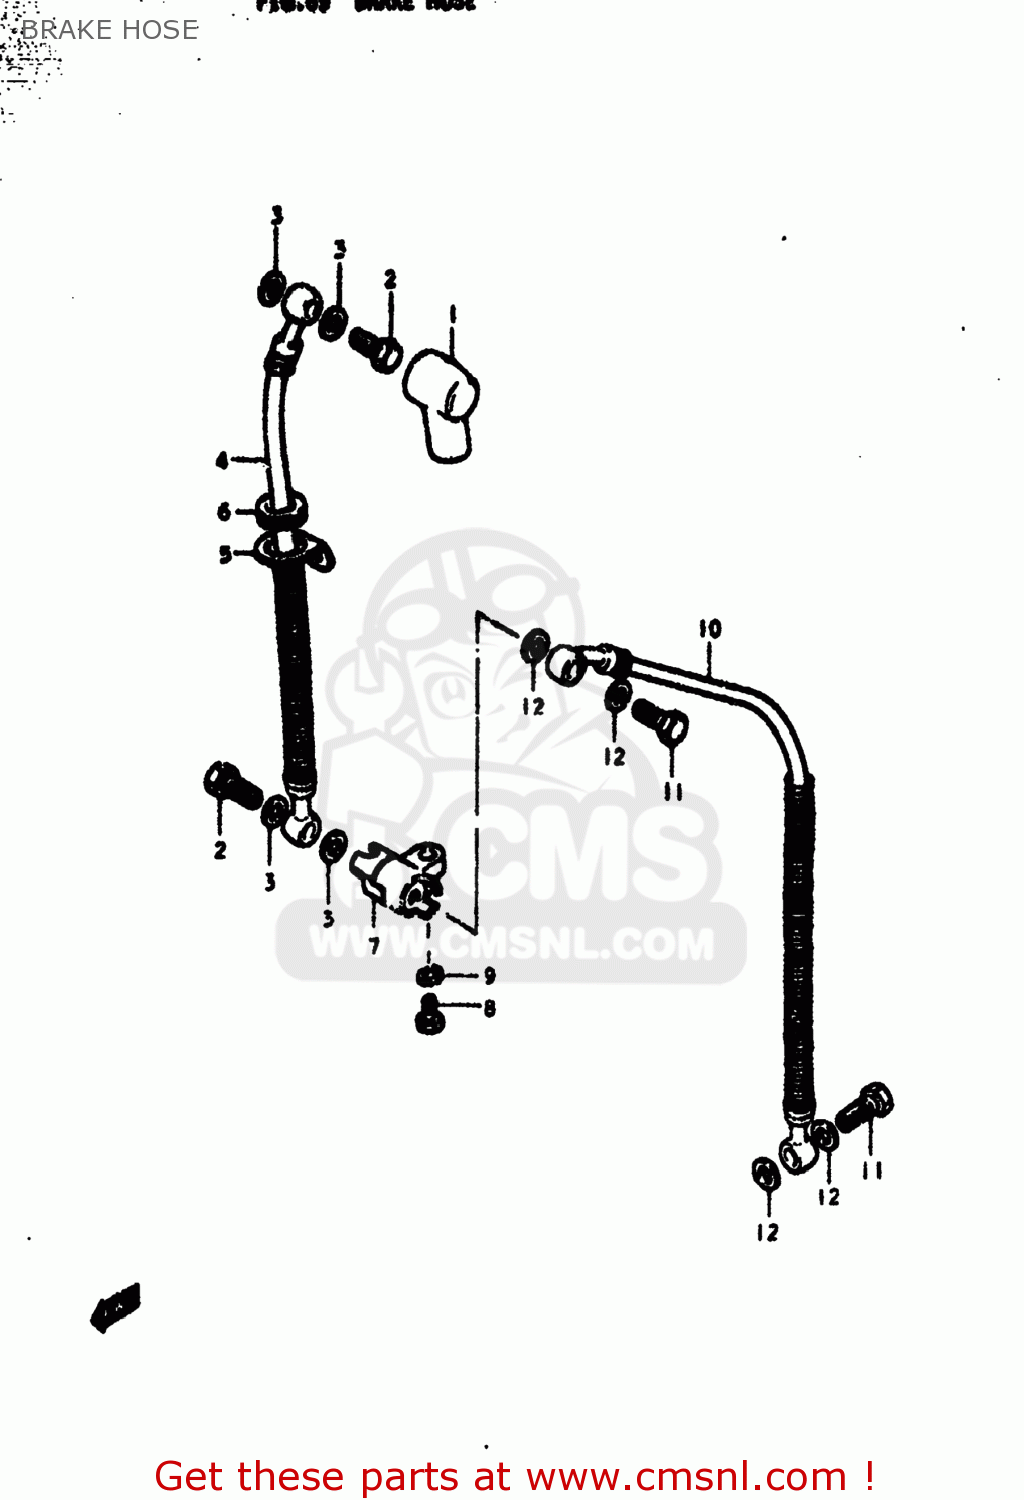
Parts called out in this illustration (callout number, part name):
1	BOOT,MASTER CYLINDER
2	BOLT UNION
3	WASHER
4	HOSE,BRAKE NO.1
5	GUIDE,BRAKE HOSE
6	GROMMET
7	JOINT,BRAKE HOSE
8	BOLT
9	LOCK WASHER
10	HOSE,FRONT BRAKE
11	BOLT UNION
12	WASHER
